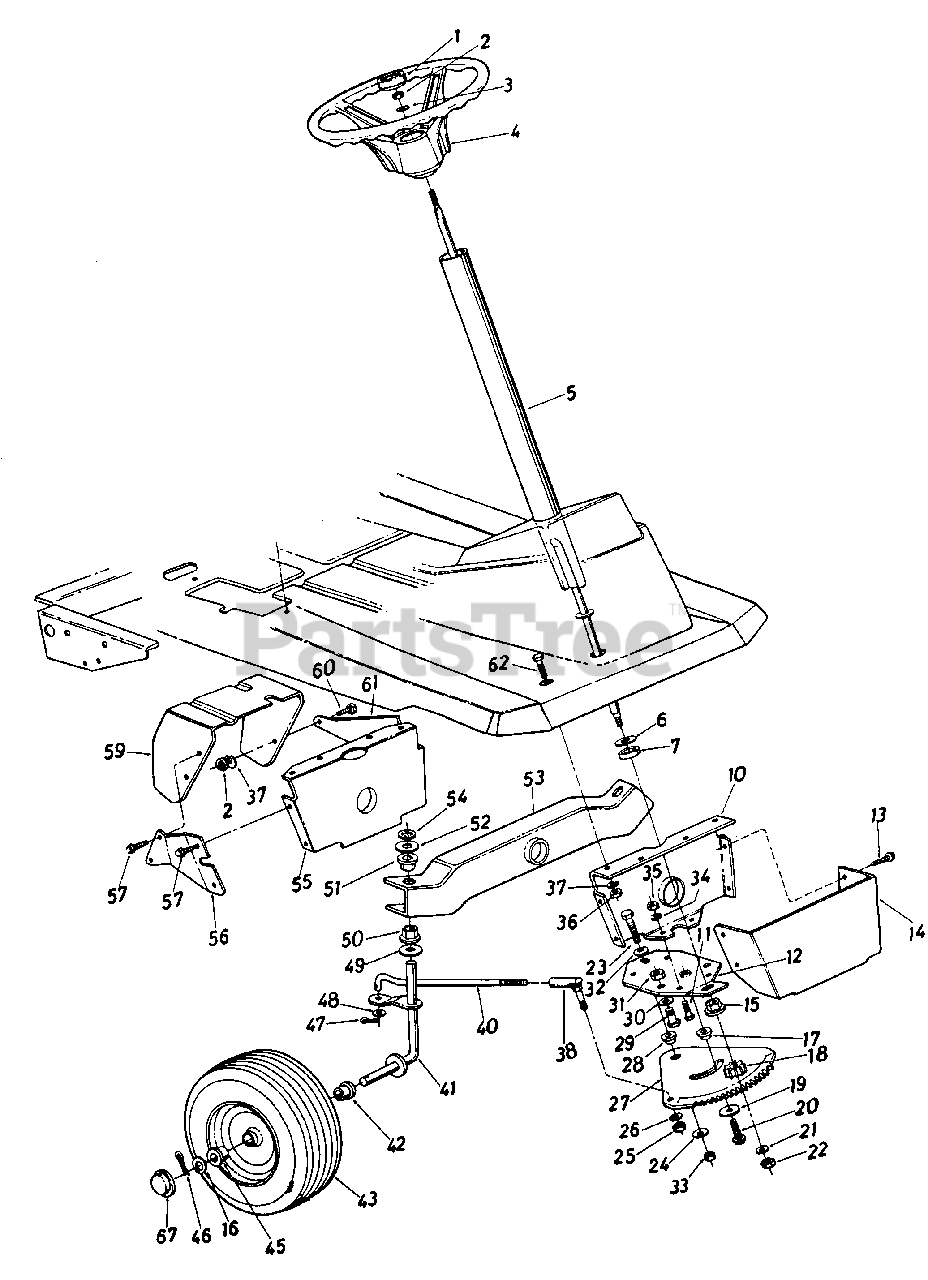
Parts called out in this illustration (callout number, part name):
1	CAP-STEER WHEEL
2	NUT-HEX 5/16-18
3	WASHER-BELL .337 X .867 X .057
4	STEERING WHEEL ASSY
5	SHAFT ASSY
6	WASHER-FL-.640ID X 1.24OD X .06HDN
7	SPACER
10	BRACKET-PIVOT BAR
11	SCREW-HEX 5/16-18 X .75
12	BRACKET-ST GEAR SUP
13	SCREW-HEX WASH HD
18	GEAR-PINION
20	SCREW-HEX SLF TAP 3/8 X 1 3/8
21	WASHER-BELL .337 X .867 X .057
22	NUT-5/16-24
23	SCREW 3/8-24X1.25 GR5
25	NUT-HEX 3/8-24
26	WASHER-LOCK-3/8
27	SEGMENT-STEERING
29	SCREW-NYLON
30	WASHER-FL-.531 X .930 OD X .050
31	NUT-HEX 1/2-13
32	WASHER-BELL .400 ID X .88 X .060
33	NUT-HEX 3/8-24
34	WASHER-LOCK-5/16
35	NUT-HEX 5/16-18
38	JOINT ASSY-BALL
40	ROD-STEER TIE
42	BEARING-FLANGE
43	WHEEL ASSY W/TIRE-10.5 X 3.5
43	FITTING-GREASE
46	PIN-COTTER-1/8 DIA X 1.25
47	PIN-COTTER-1/8 DIA X 1.00
48	WASHER-FL-.385 ID X .87 OD X .06
49	WASHER-FL-.635 ID X 1.12 OD X .090
50	BEARING-FLANGE
52	WASHER-FL-.635 ID X 1.12 OD X .090
53	BAR ASSY-PIVOT
54	NUT-PUSH-SPEED
55	BRACKET-PIVOT BAR
56	BRACKET-REINF-RH
57	SCREW-HEX WASH HD
59	PEDAL ASSY-BRAKE
60	SCREW-HEX 5/16-18 X .75
61	BRACKET-REINF-LH
62	SCREW-HEX 5/16-18 X .75
63	HUB CAP
